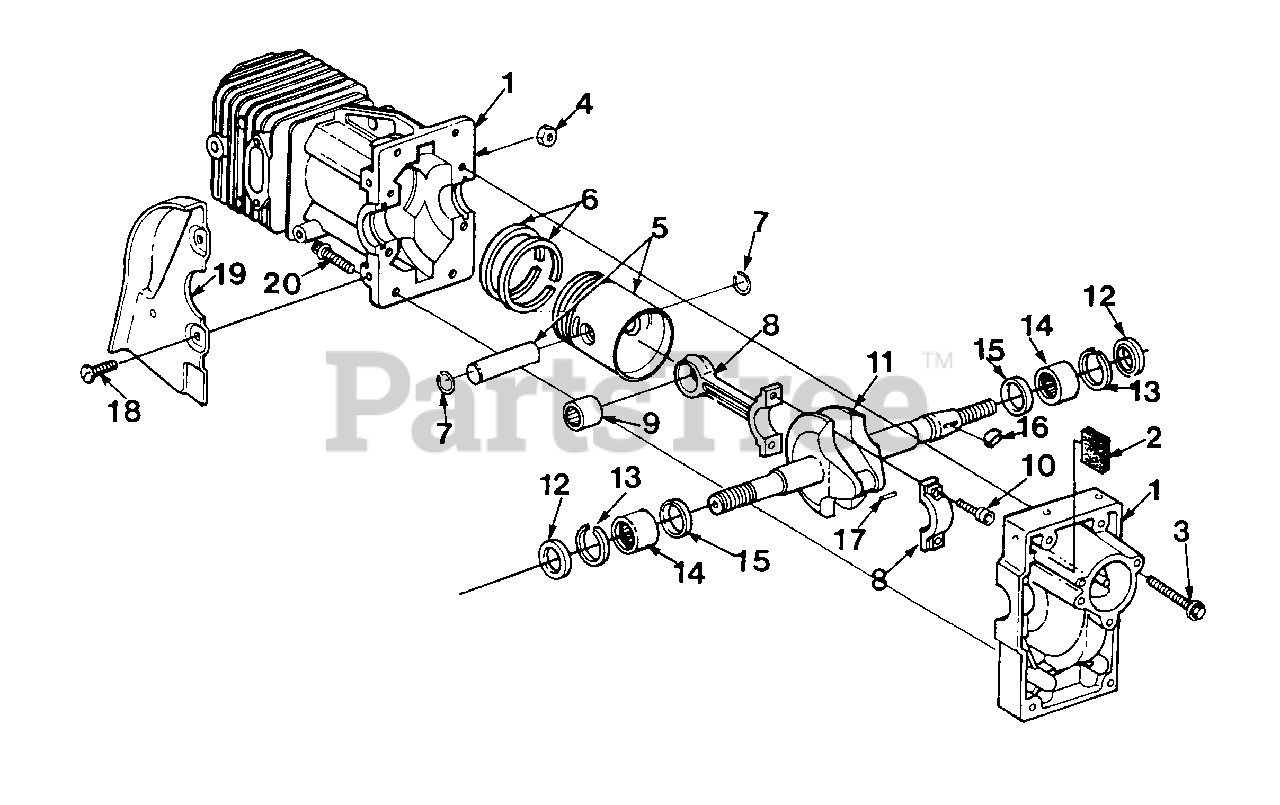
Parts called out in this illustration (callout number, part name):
1	CRANKCASE & CYLINDER
2	COVER- Vent
3	SCREW- Hex washer hd. 8-32 x 1
4	NUT- Hex centerlock 8-32
5	PISTON & PIN
6	PISTON- Ring
7	RING- Piston retaining
8	ROD- Connecting
9	BEARING- Needle
10	SCREW- Soc. hd., 8-32 x 1/2
11	CRANKSHAFT
12	SEAL
13	RING- Retaining
14	BEARING- Roller
15	BEARING- Thrust
16	KEY- Woodruff
17	ROLLER- Needle (set of 18)
18	SCREW- Pan taptite 8-32 x 5/16
19	SHIELD- Sawdust
20	SCREW- Hex hd. 8-32 x 3/4
